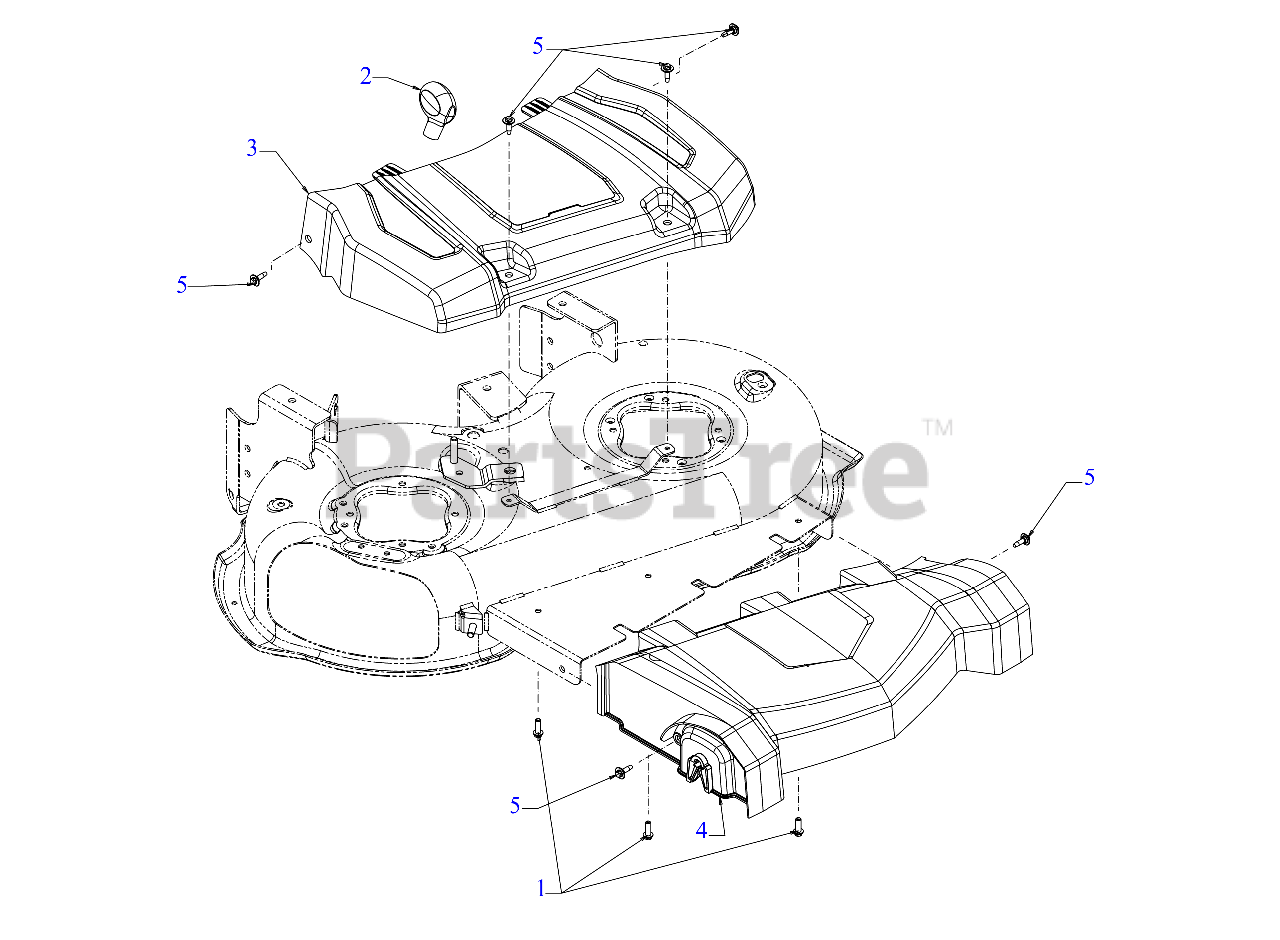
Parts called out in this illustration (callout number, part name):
1	SCREW 1/4 x .750
2	HEIGHT ADJUSTMENT KNOB (SBD GRAY)
3	28" BELT COVER
4	FRONT AXLE COVER
5	SHOULDER SCREW M6-1 .368 X.115
